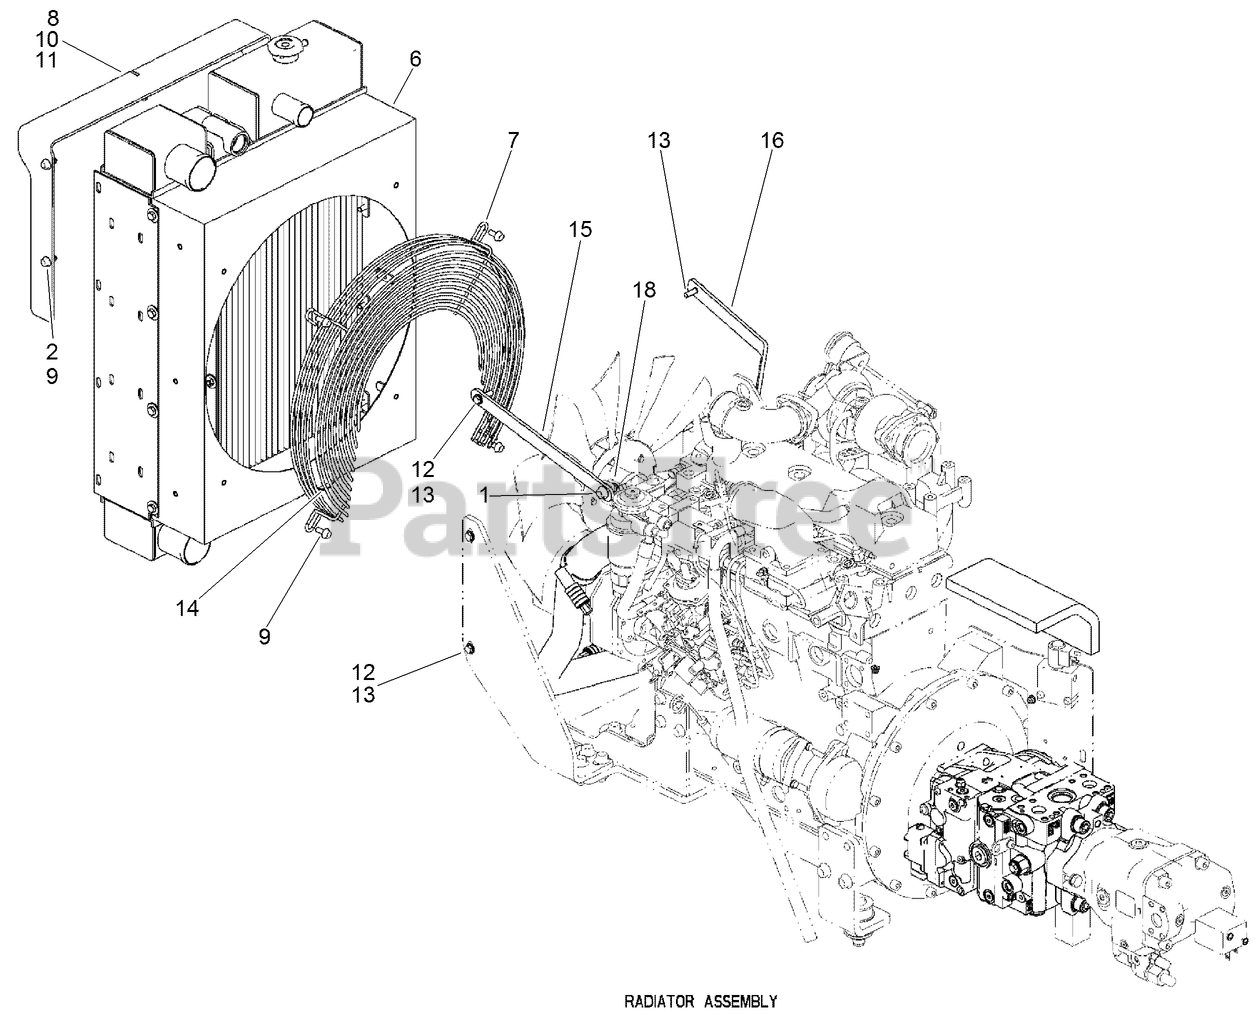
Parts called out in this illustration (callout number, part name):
1	SCREW-HH
2	NUT, METRIC FLANGE PREVAILING - M6 Zinc
6	COOLER ASM
7	GUARD-Fan
8	ASSEMBLY - Shock Mount
8	SHOCK MOUNT ASM
9	SCREW, METRIC FLANGE w/BODY - M8 x 20
10	STUD-BALL
11	NUT - Prev Trq 5/16 GRB ZND Direct
12	WASHER-FLAT
13	BOLT-Hex, 5/16 NC x 1-1/4 inch
14	PLUG - Hdls Hex Skt Pipe 1/4 ZN
15	PLATE - Radiator Strap Mount
16	PLATE - Radiator Strap Mount
18	NUT-FLANGE, NYLOCK
